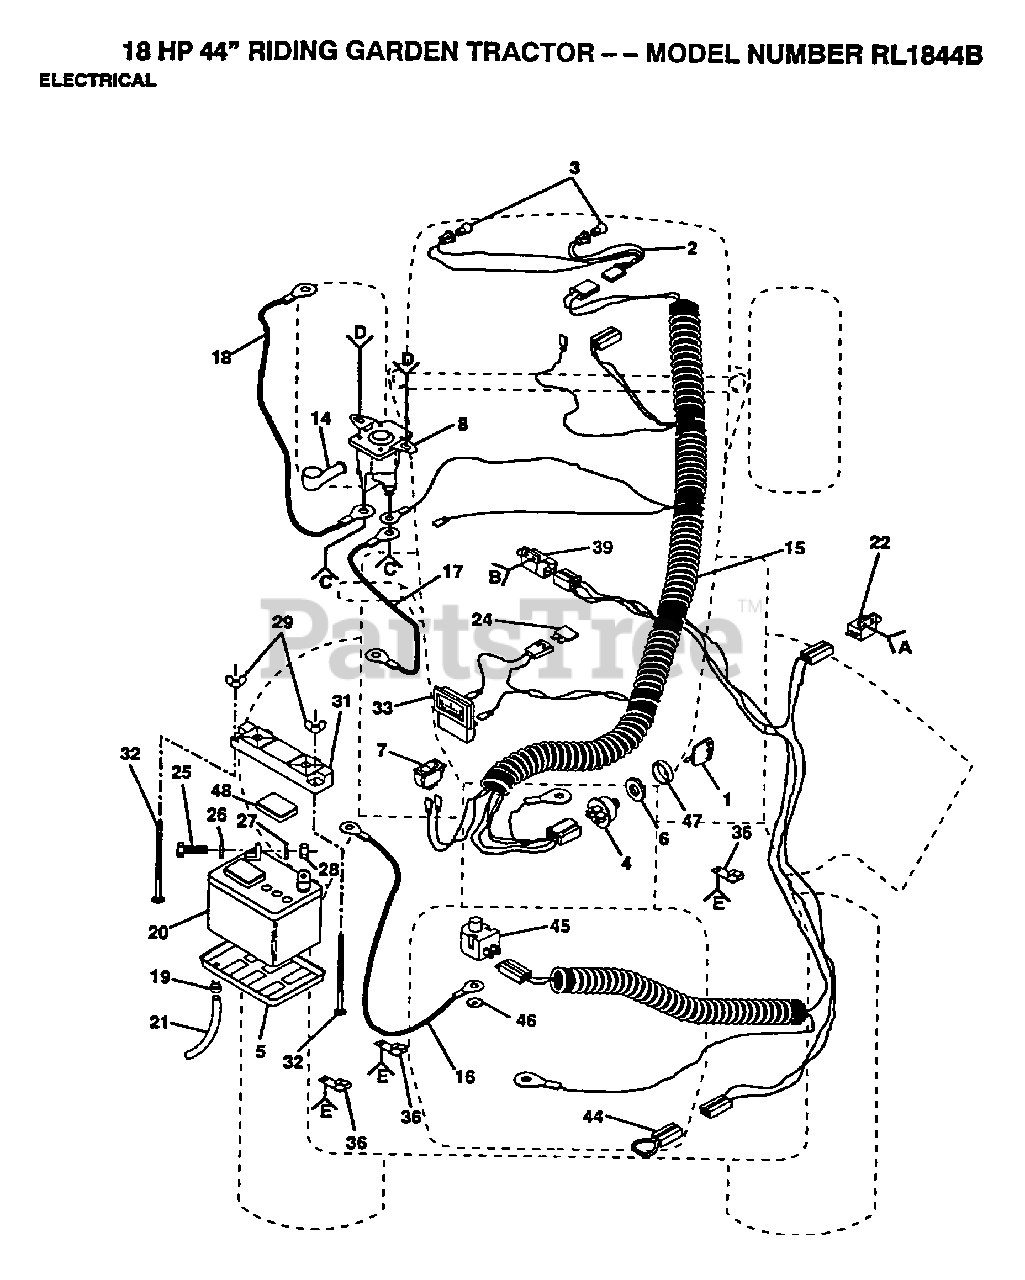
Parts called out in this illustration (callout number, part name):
1	KEY
2	HARNESS T
5	"TRAY T, BATTERY"
7	SWITCH LT
10	NUT
11	BOLT
13	NUT
15	HARNESS
16	"CABLE T, BATTERY"
17	CABLE LT
18	CABLE T
19	HOSE CLAMP T
22	SWITCH-INTER. GT
23	SCREW
24	FUSE HYT
25	BOLT LT
26	WASHER
27	LOCKWASHER
32	BOLT
36	CLIPT
39	SWITCH INTERLOCKT
42	SCREW
43	"NUT,KEPS"
45	SWITCH SEAT
46	LOCKWASHER
48	"CAP,BATTERY "
